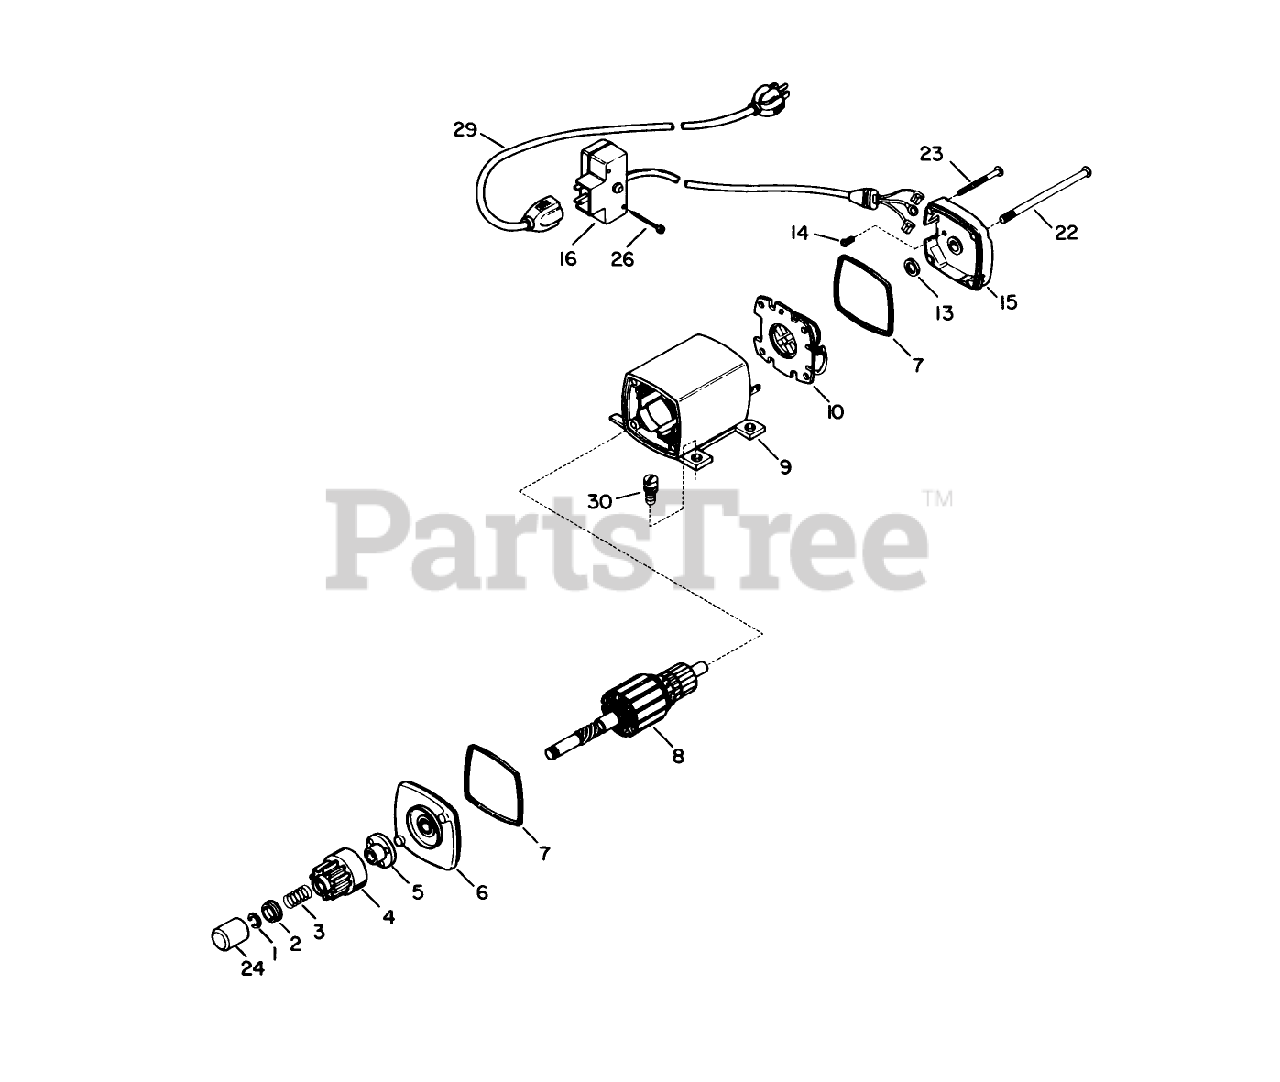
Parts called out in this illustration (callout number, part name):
1	Ring-Retainer
2	Retainer-Spring
3	Spring-Anti Drift
4	Gear
5	Nut-Engaging
6	Cap Assembly-Cap End (Incl. Ref. #7)
7	O-Ring
8	Armature
9	Housing ASM
10	Card ASM
13	Washer-Thrust
14	Screw-Ground
15	Cap Assembly (Incl. Ref. #7)
16	Box Assembly-Switch (Incl. Ref. #26)
22	Bolt-Case
23	Screw-Ground
24	Cover-Dust
26	Screw
29	Cord-Extension
30	Screw
